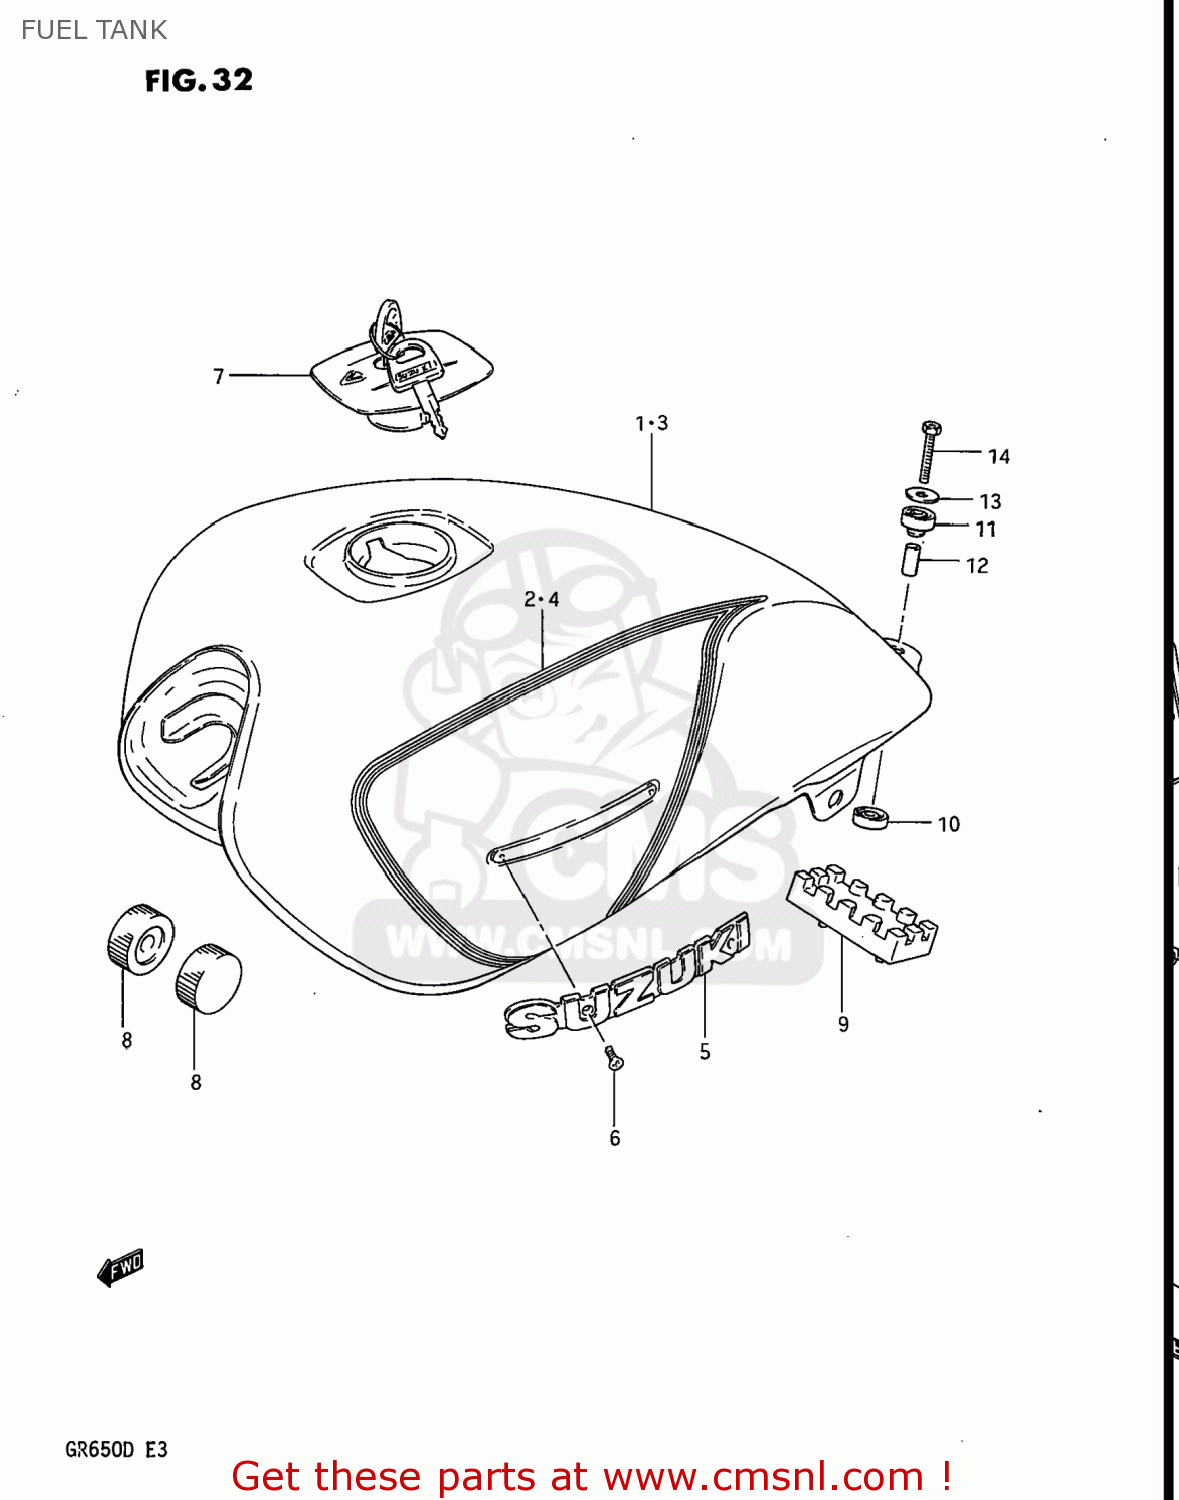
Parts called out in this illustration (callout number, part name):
1	TANK ASSEMBLY,FUEL
2	TAPE SET,FUEL TANK
3	TANK ASSEMBLY,FUEL
4	TAPE SET,FUEL TANK
5	EMBLEM,FUEL TANK
6	SCREW 3X6
7	CAP SET,FUEL TANK
8	CUSHION
9	CUSHION,FUEL TANK CTR
10	CUSHION
11	CUSHION
12	SPACER
13	WASHER (6.5X24X1.6)
14	BOLT
